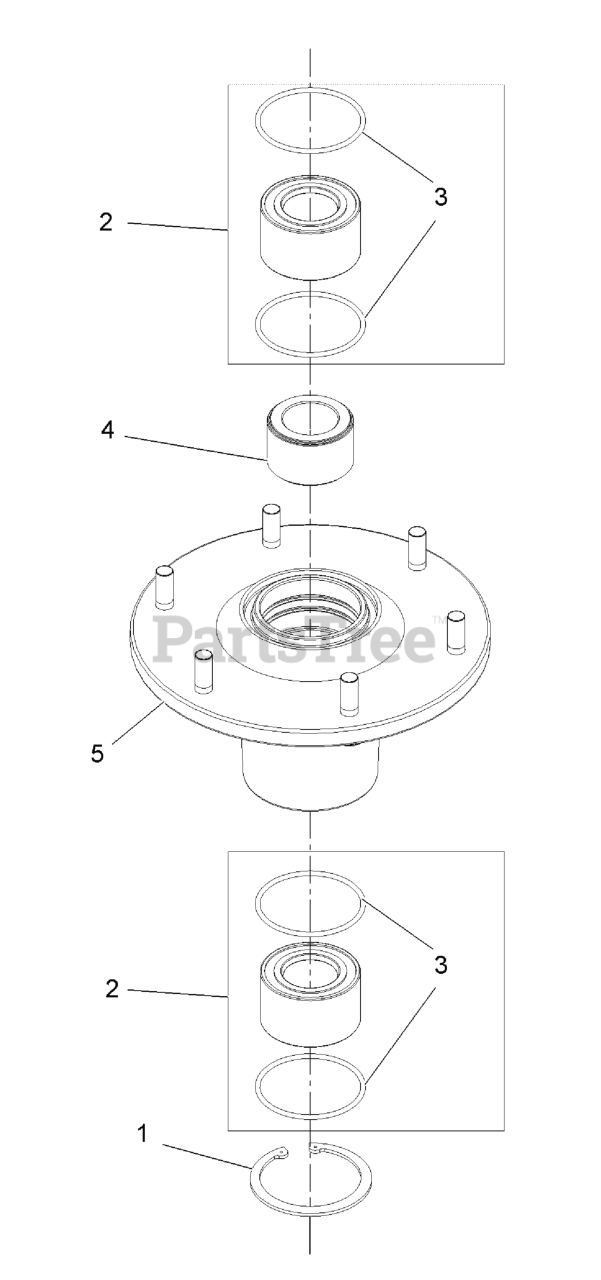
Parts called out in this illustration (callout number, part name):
1	RING-RETAINING
2	ASM, BEARING W/ORINGS
4	SPACER,BEARING
5	ASM,HOUSING W/STUDS
